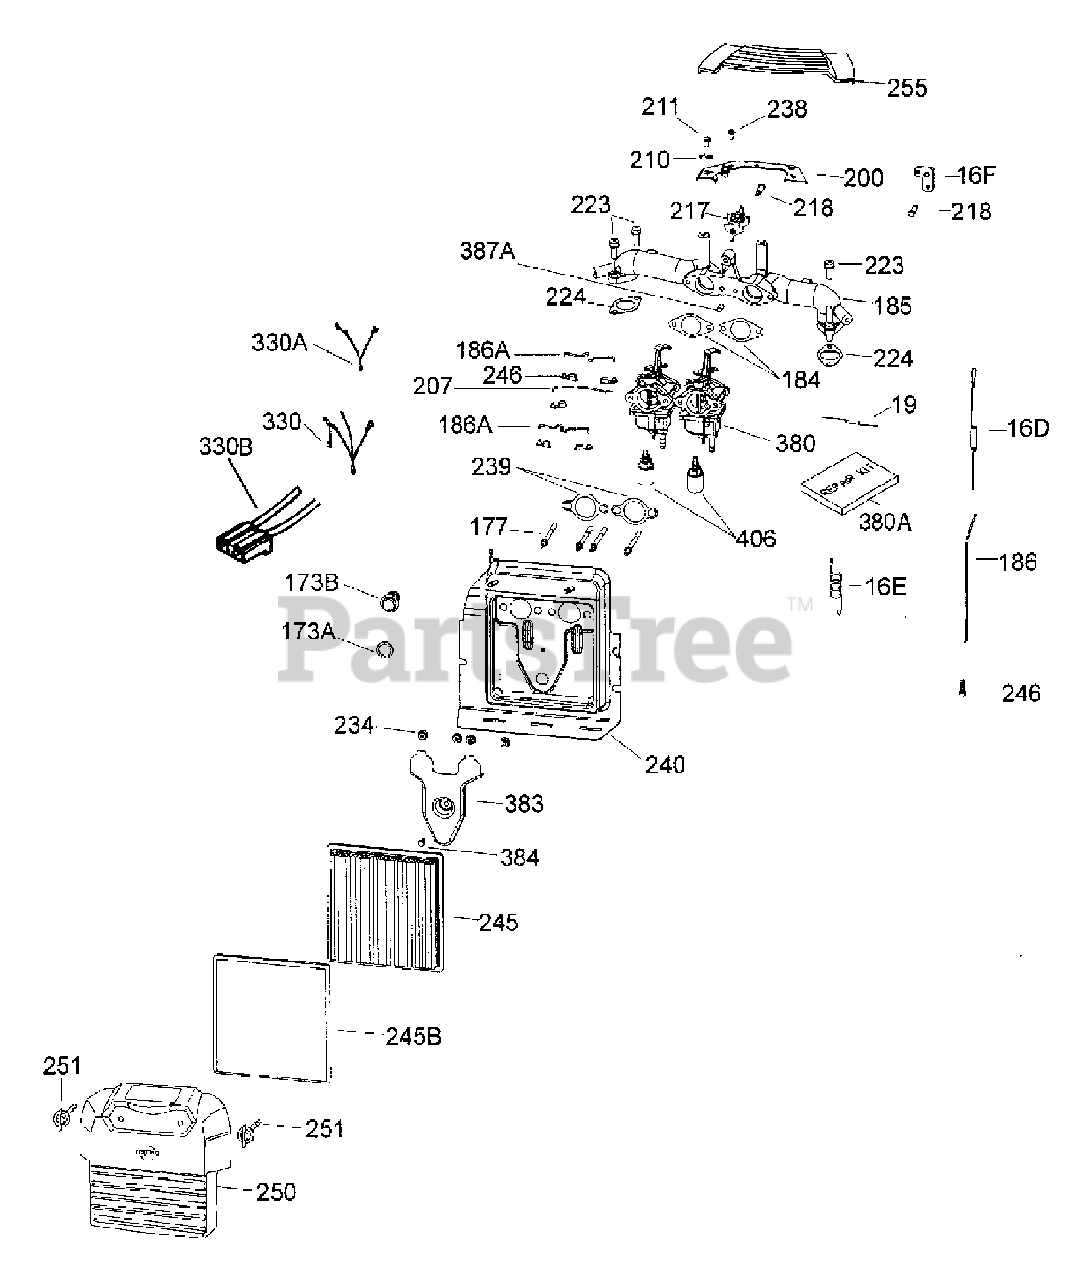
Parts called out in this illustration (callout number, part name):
16D	Governor Spring, Hi-speed
16E	Governor Idle Spring
16F	Bell Crank Lever
19	Throttle Spring
173A	Breather Tube Grommet
173B	Breather Tube Fitting
177	Carburetor Mounting Stud
184	Carburetor to Intake Pipe Gasket
185	Intake Pipe
186	Governor Link
200	Control Bracket
207	Throttle Link
210	Conduit Clip
211	Screw, 10-32 x 3/8"
217	Control Lever
218	Screw, 10-32 x 1-1/4"
223	Screw, T-30 5/16-18 x 7/8"
224	Intake Pipe Gasket (Pipe to Head)
234	Lock Nut, 1/4-20
238	Screw, 10-32 x 7/16"
239	Air Cleaner Gasket
240	Air Cleaner Body Ass'y.
245	Air Cleaner Filter (Paper)
245B	Air Cleaner Pre-Filter (Poly)
246	Connector Bushing Link
250	Air Cleaner Cover
251	Wing Nut, 1/4-20 x 1-19/32"
255	Control Cover
330	Fuel Solenoid Wire Assembly (R & G)
330A	Fuel Solenoid Wire Assembly (Black)
380	Carburetor
380A	Carburetor Repair Kit
383	Carburetor Baffle
384	Screw, 10-24 x 9/16" Self Tap
406	Fuel Shut-Off Solenoid
